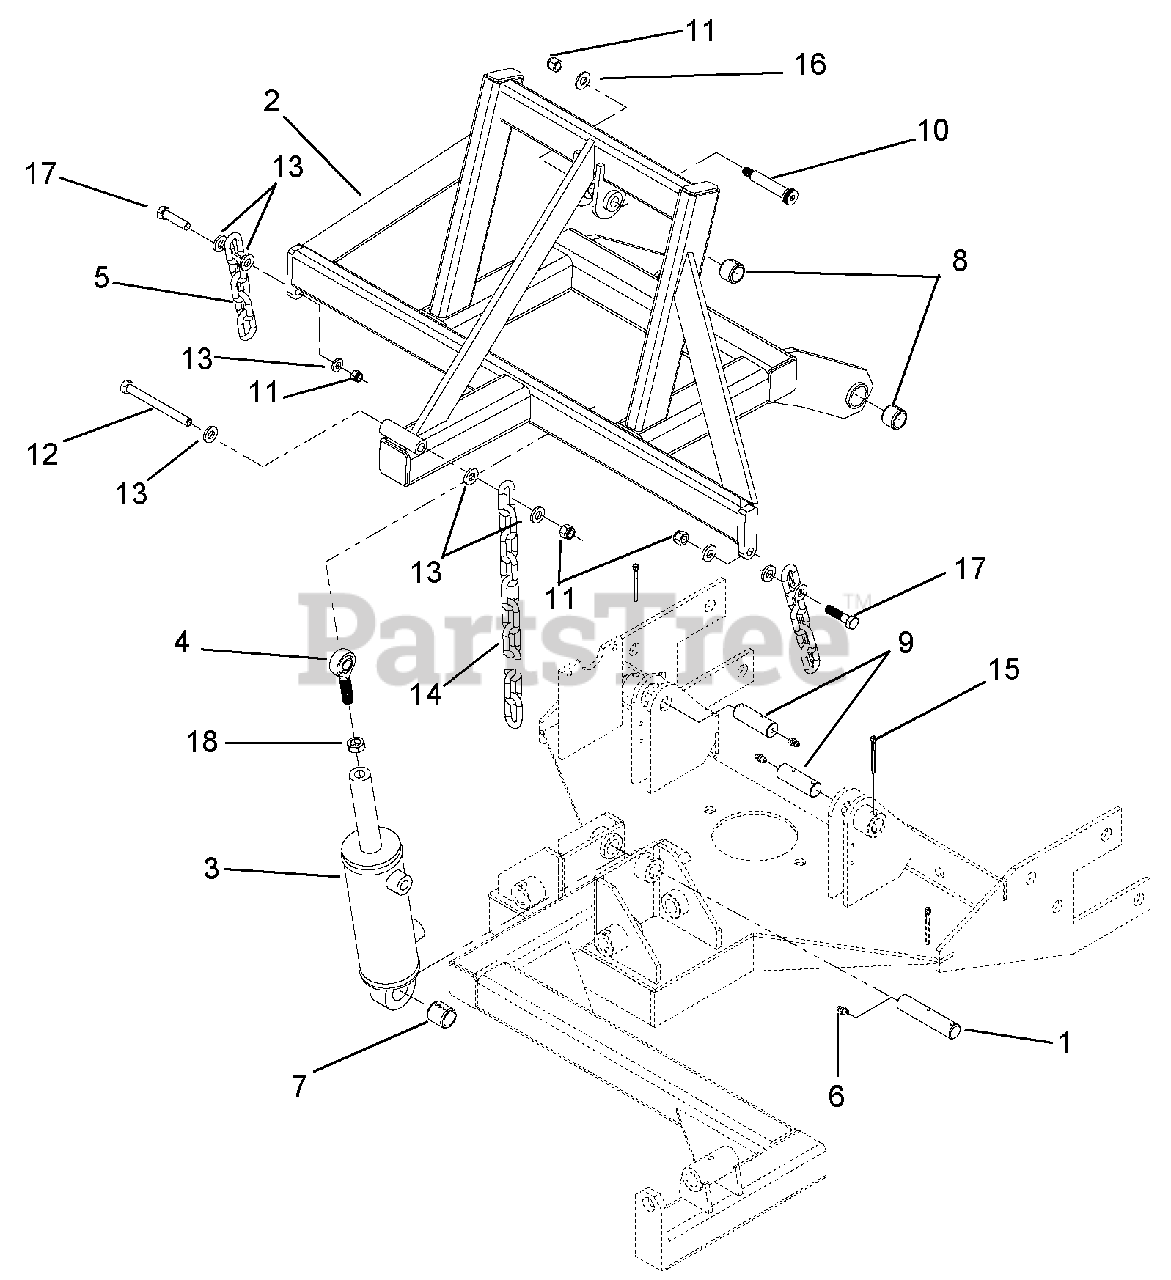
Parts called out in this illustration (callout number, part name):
1	PIVOT PIN (CYLINDER)
2	REEL LIFT WELDMENT
3	HYDRAULIC CYLINDER 2-1/2 BORE X 4 STROKE
5	CHAIN - 5 LINK
6	GREASE FITTING, 1/4-28
7	BUSHING, 1 X 3/4 X 1
8	BUSHING, 1 X 3/4 X 3/4
9	PIN, CENTER ARM
10	HEX SOC HD SHOULDER BOLT, 1/2 X 2-1/4 X 3/8-16
11	HEX NUT, 3/8-16 NYLOCK
12	HHCS, 3/8-16 X 3-1/2
13	FLATWASHER, 3/8 HARDENED
14	CHAIN - 11 LINK
15	COTTER PIN, 3/16 X 1-1/2
16	FLATWASHER, 3/8
17	HEX CAP SCREW 3/8-16 X 1-1/5
18	HEX JAM NUT 1/2-20
